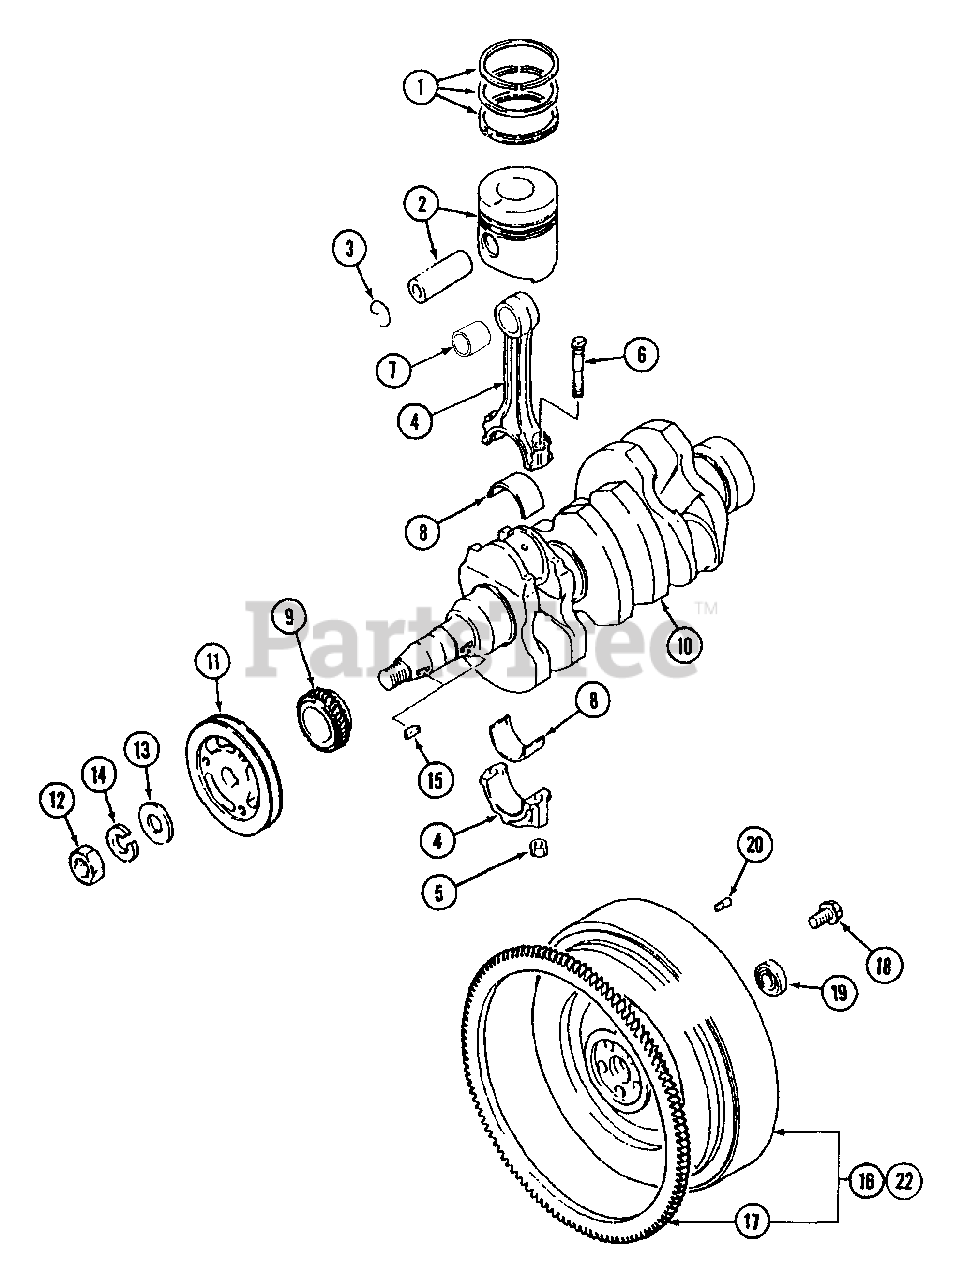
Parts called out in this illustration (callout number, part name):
1	Ring Set, Piston STD
2	Piston & Pin Set STD
3	Clip, Piston Pin
4	Cap, Connecting Rod
5	Nut, Con.Rod
6	Bolt, Con. Rod
7	Rod
8	Bearing Set, Con. Rod STD
9	Gear, Crankshaft
10	Crankshaft
11	Pulley, Crankshaft
13	Washer, Plain
14	Washer,Spring
15	Key, Woodruff
16	Flywheel Sub Ass'y.
18	Bolt, Drive Plate
19	Bearing, Ball
20	Pin, Dowel
22	Flywheel Sub Ass'y.
